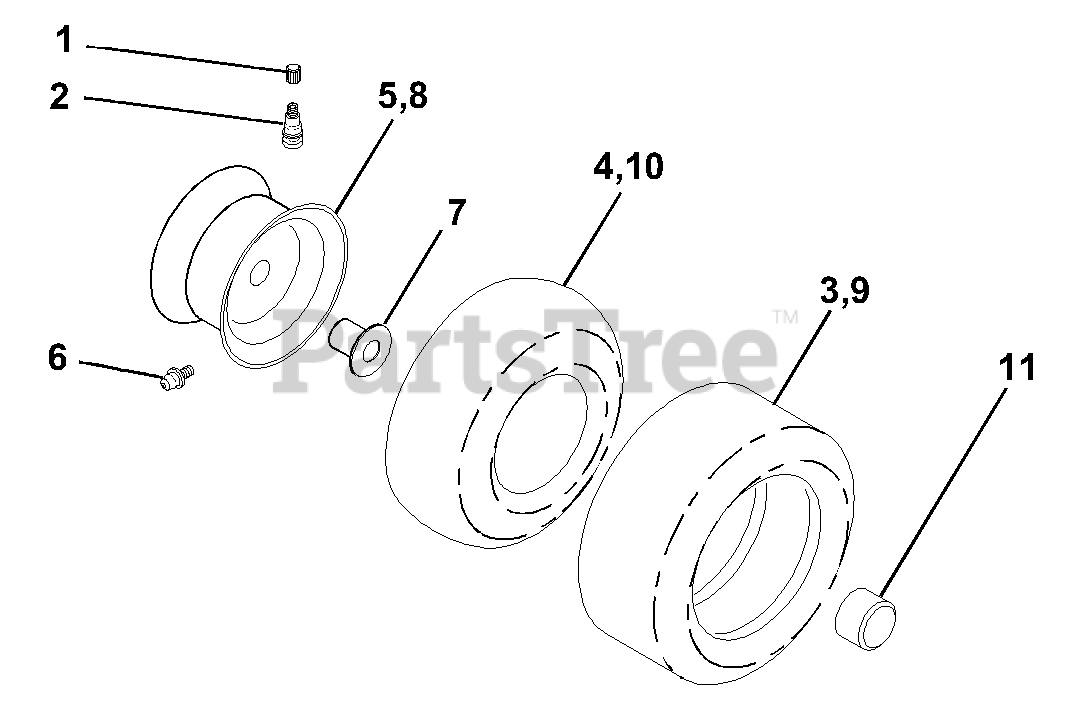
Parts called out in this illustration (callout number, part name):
1	Cap Valve Tire
2	Stem Valve
3	Tire F Ts 15 X 6 0 - 6 Service
4	Tube Front
5	Rim Asm 6" front White Service
6	Fitting Grease
7	Bearing Flange
8	Rim Asm 8" rear White Service
9	Tire R Ts 18 x 9.5-8 C Service
10	Tube Rear
11	Cap Axle Blk 1 50 X 1 00
